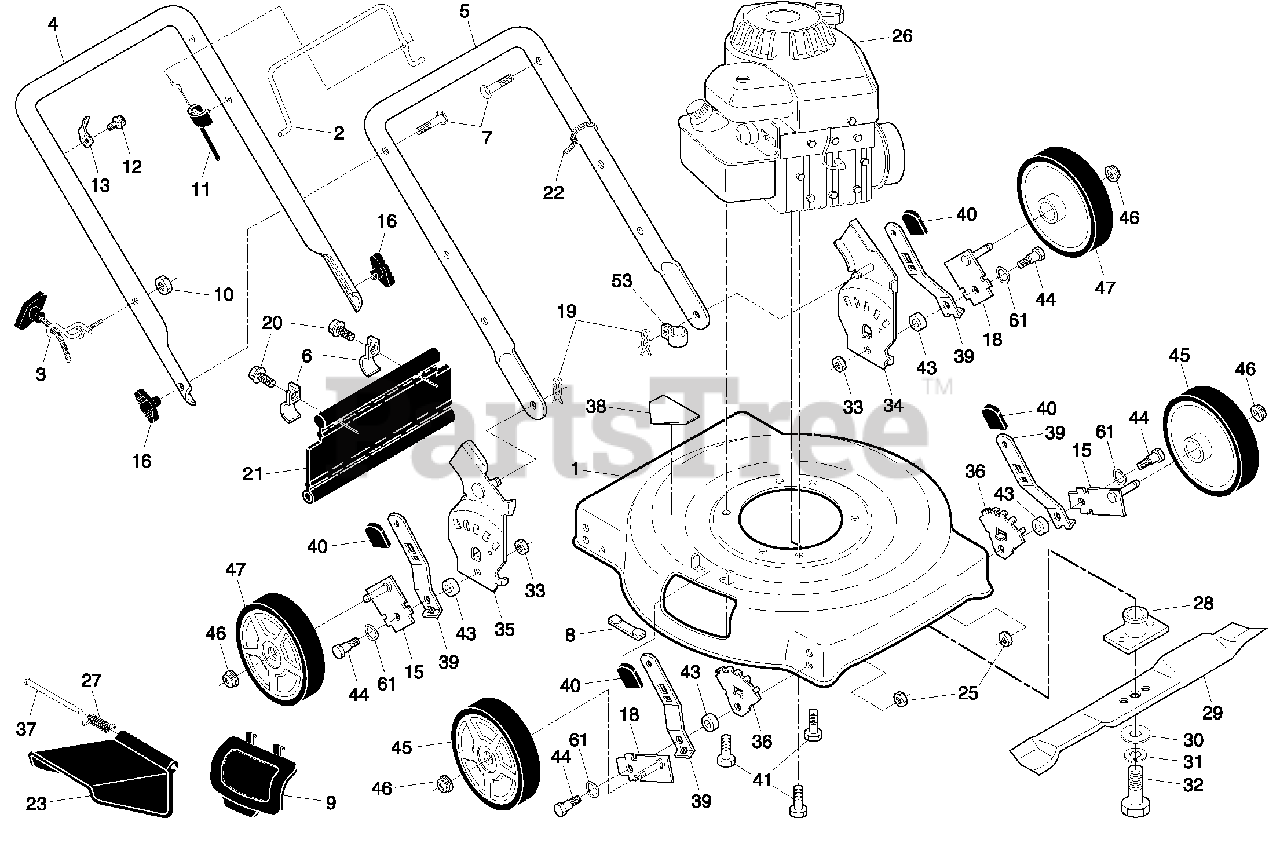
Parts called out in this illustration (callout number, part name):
1	Lawn Mower Housing Assembly
2	Control Bar
3	Rope Guide
4	Upper Handle
5	Lower Handle
6	Hinge Bracket
7	Handle Bolt 5/16-18
8	Clip, Closeout
9	Mulcher Plate
10	Locknut, Hex 1/4-20
11	Engine Zone Control Cable
12	Screw, Hex Head, Threaded, Rolled #10-24 x1/2
13	Up-Stop Bracket
15	Axle Arm Assembly (Rear, RH / Front, LH)
16	Handle Knob
18	Axle Arm Assembly (Rear, LH / Front, RH)
19	Hairpin Cotter
20	Screw
21	Rear Skirt
22	Wire Tie
23	Discharge Guard
25	Nut, Hex
27	Torsion Spring
28	Blade Adapter
29	22" Blade
30	Hardened Washer
31	Helical Lockwasher 3/8
32	Hex Head Screw 3/8-24 x 1/4 Grade 8
33	Nut, Hex, Centerlock 5/16-18
34	Support, Wheel Bracket, LH
35	Support, Wheel Bracket, RH
36	Adjuster, Wheel Bracket
37	Hinge Rod
38	Danger Decal
39	Selector Spring
40	Selector Knob
41	Screw, Hex Head, Threaded, Rolled 3/8-16 x 1
43	Spacer
44	Shoulder Bolt
45	Wheel & Tire Assembly, Front
46	Locknut, Hex 3/8-16
47	Wheel & Tire Assembly, Rear
53	Clip, Cable
61	Washer, Curved, Cylindrical
61	Operator's Manual, English
61	Operator's manual, Spanish
61	Repair Parts Manual
